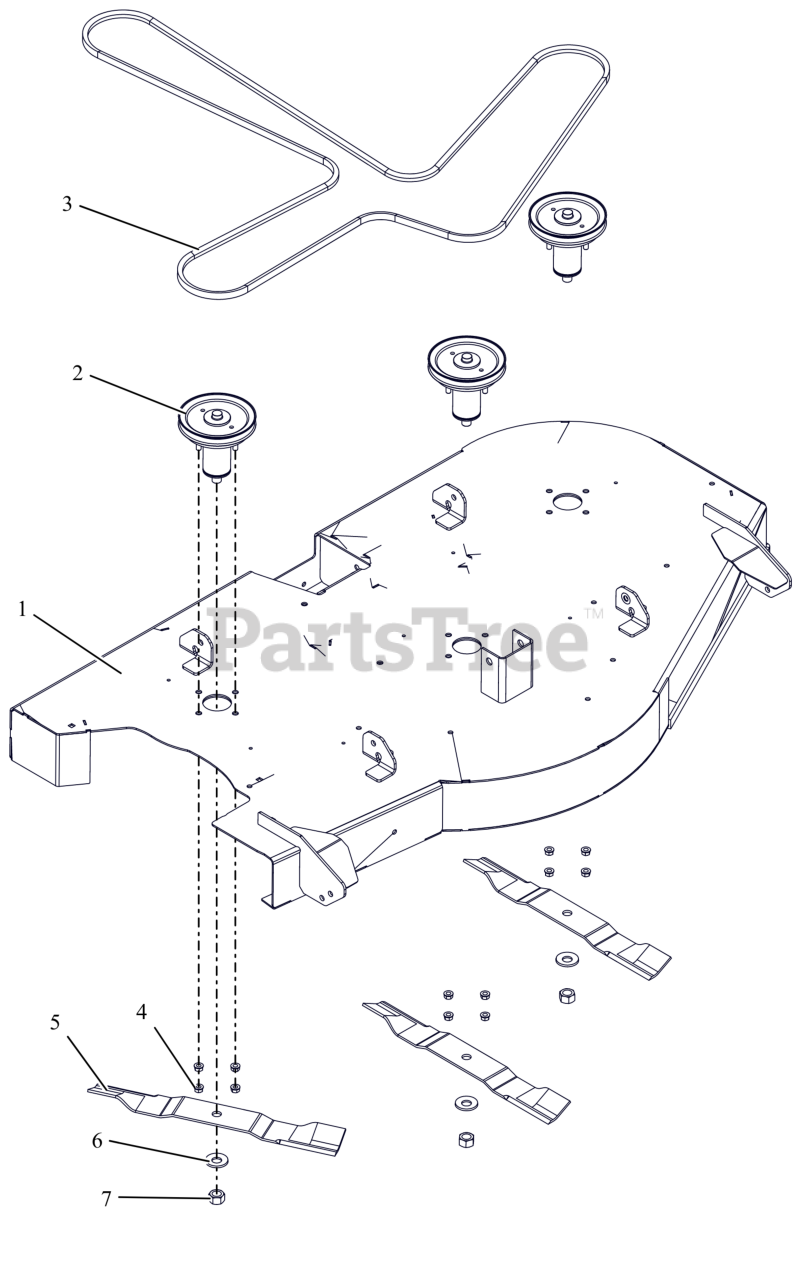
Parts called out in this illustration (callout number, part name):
1	KIT- 52" EDGE DECK W/DECALS
2	KIT- DECK SPINDLE ASSM- 52"
3	V-BELT, HA-WRAPPED
4	NUT,LK-CTR-FLG .31-18 GF ZCC
5	BLADE, 18" - 30 DEG .5 OFFSET
6	WSHR-BLVL .669X1.535X.138
7	NUT-STD .625-18 ZCC
